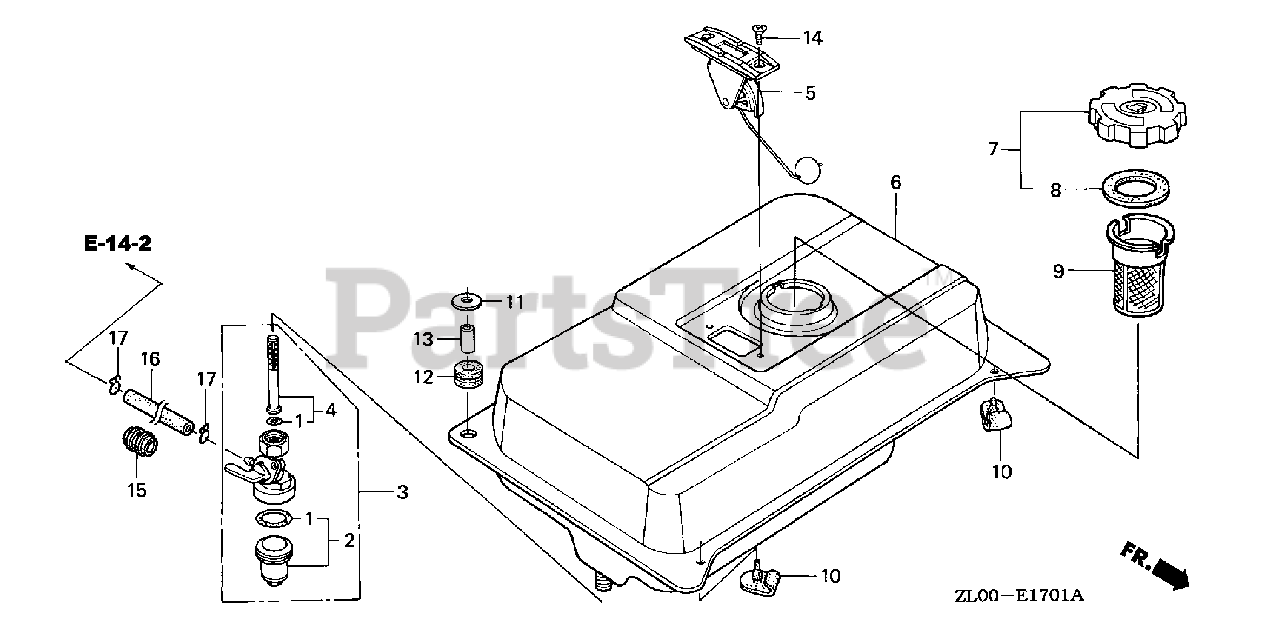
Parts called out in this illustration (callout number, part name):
1	GASKET SET, PETCOCK (CONTAINS 1 LARGE & 1 SMALL; USE AS NEEDED)
2	CUP, FUEL STRAINER
3	PETCOCK ASSY.
4	SCREEN SET
5	METER ASSY., FUEL
6	TANK, FUEL *R8* (BRIGHT RED)
7	CAP, FUEL FILLER
8	GASKET, FUEL FILLER CAP
9	FILTER, FUEL
10	RUBBER, TANK MOUNTING
11	WASHER, FLAT (20MM)
12	RUBBER, CONTROL BOX
13	COLLAR, CONTROL BOX
14	SCREW, FLAT (5X10)
